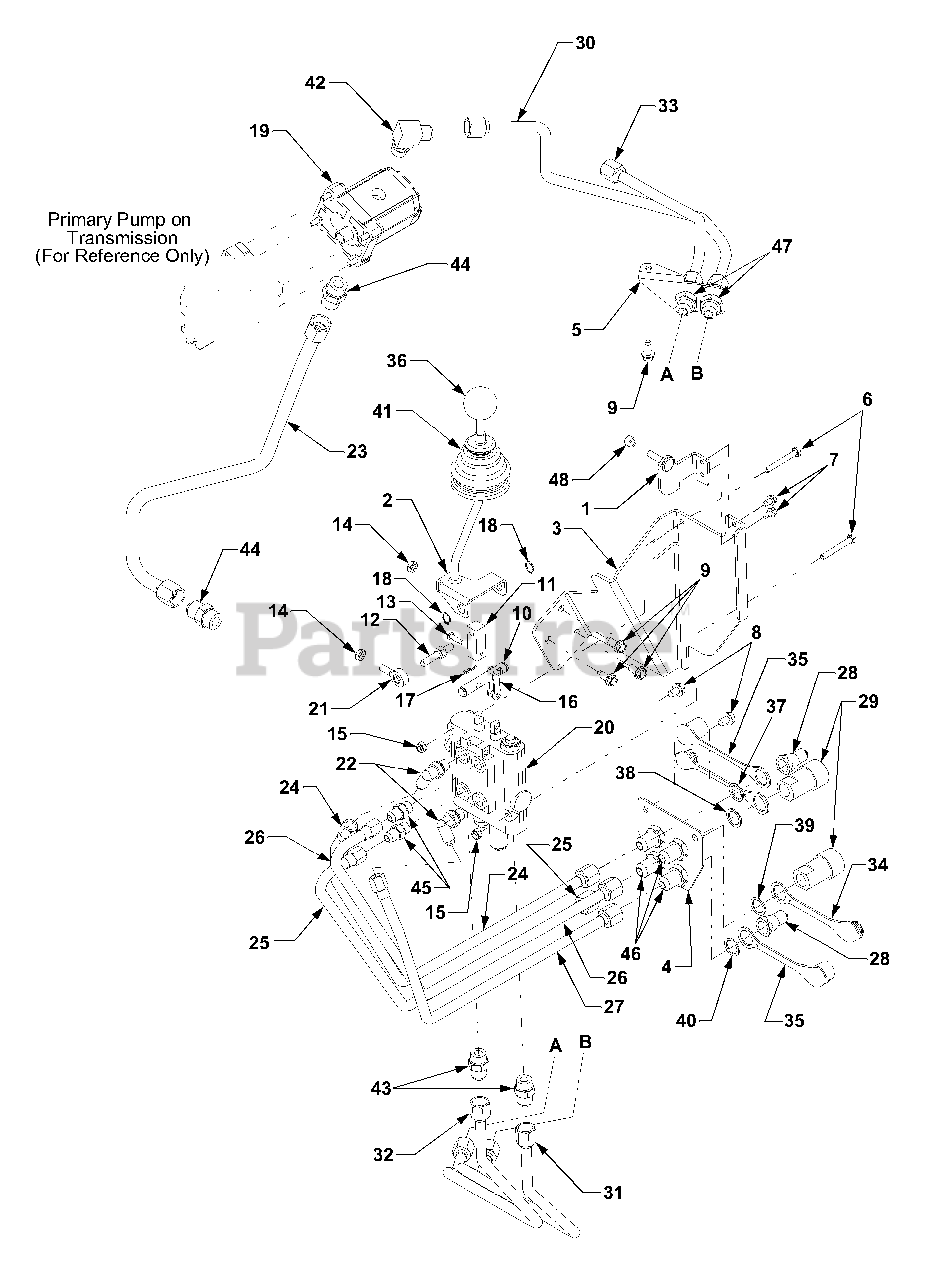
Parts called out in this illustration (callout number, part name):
1	Pivot Bracket Assembly
2	Valve Handle Assembly
3	Loader Valve Mount Bracket
4	Fitting Mount Plate
5	Rear Fitting Mount Plate
6	Hex Screw, 1/4-20, 2.00, Gr5
7	Hex Wash. Hd. Tapp Screw 1/4-20 x .50
8	Hex Wash. Hd. Tapp Screw 5/16-18 x .625
9	Hex Wash. Hd. Tapp Screw 5/16-18 x .75
10	Valve Pivot Shaft
11	Valve Spool Link
12	Ball Joint Pivot Stud
13	Clevis Pin, .199 x .8125
14	Jam Nut, 5/16-24, Gr2
15	Hex Lock Nut, 1/4-20, Gr8, Nylon
16	Chain Link
17	Internal Cotter Pin
18	Snap Ring, .5
19	Auxiliary Hydraulic Pump
20	Loader Control Valve
21	Ball Joint, .3125 Id x 5/16-24
22	Fitting, 90° 6-6 Orb
23	Tube, Tandum Pump Suction
24	Tube, Hydraulic - Bucket Rollback
25	Tube, Hydraulic - Bucket Dump
26	Tube, Hydraulic - Boom Lift
27	Tube, Hydraulic - Boom Lower
28	Coupling, Male Hydraulic, 3/8-18
29	Coupling, Female Hydr. 3/8-18
30	Tube, Auxiliary Pump Pressure
31	Tube, Valve Pressure
32	Tube, Valve Return
33	Tube, Valve Return
34	Plug, Hydraulic Coupler - Male
35	Plug, Hydraulic Coupler - Female
36	Knob, 1.625 Dia x 3/8-16 Thd
37	Washer, Indicator - Red
38	Washer, Indicator - Yellow
39	Washer, Indicator - Green
40	Washer, Indicator - Blue
41	Joystick Boot
42	Fitting, 90° -8 Orb
43	Fitting, Straight -8 Orb
44	Fitting, Straight
45	Fitting, Straight - 6 Orb
46	Fitting, Bulkhead 3/4-16 x 3/8-18
47	Fitting, Bulkhead 3/4-16 x 3/4-16
48	Spacer, .34 ID x .5 OD x .31
